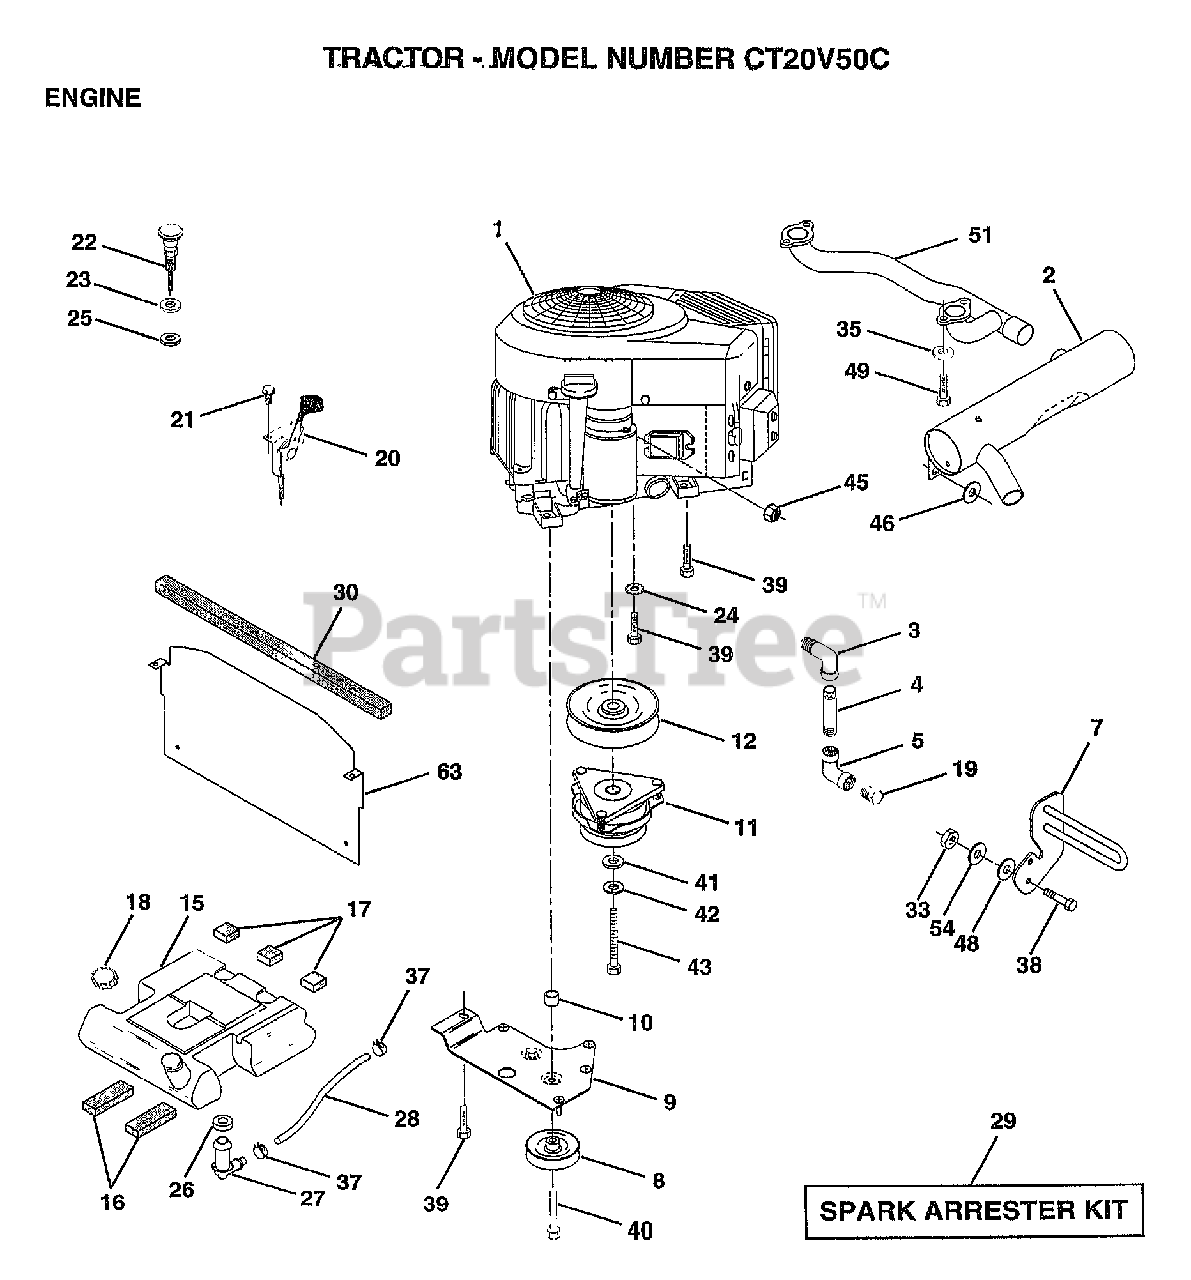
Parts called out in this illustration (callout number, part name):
3	STREET ELBOW LT
4	PIPE NIPPLE
5	ELBOW
7	GUARD.MUFFLER.ASM
9	KEEPER ASM BELT
10	BUSHING.
12	PULLEY.ENGINE.VGT
15	TANK FUEL REAR
16	PAD IDLER TI
17	PAD-SPACER LT
18	CAP ASM FUEL
19	PLUG T
21	SCREW LT
23	WASHER
24	LOCKWASHER
25	"NUT,KEPS 3/8-24IM"
26	BUSHING OUTLET T
27	STEM.TANK.FUEL
29	SPARK ARREST KIT
30	FOAM-STRIP LT
33	NUT
35	LOCKWASHER
37	HOSE CLAMP
38	"BOLT,HEX"
39	SCREW LT
40	SCREW.3/8-16X3.25
41	WASHER
42	LOCKWASHER
43	BOLT.7/16-20X4.25
45	NUT
46	WASHER HYT
48	WASHER T
49	BOLT.HD.SOCKET.
51	PIPE.EXHAUST.B&S
54	WASHER
63	SHIELD.HEAT.VGT.
